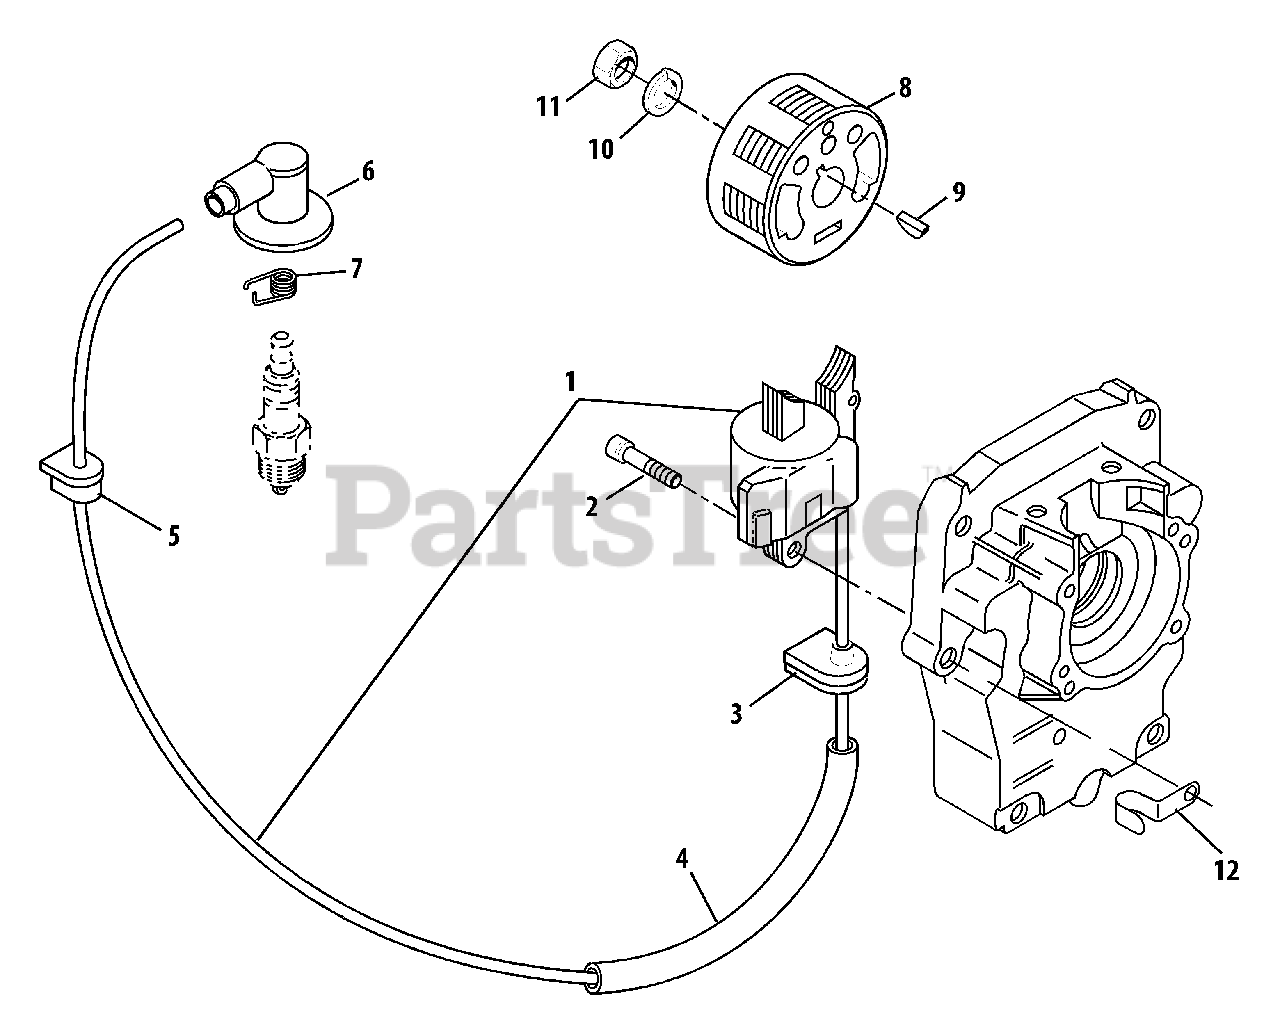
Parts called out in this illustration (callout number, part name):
1	COIL, IGNITION
2	BOLT 5
3	GROMMET
4	TUBE, INSULATOR
5	GROMMET
6	CAP, SPARK PLUG
7	TERMINAL, SPARK PLUG
8	FLYWHEEL
9	KEY, WOODRUFF 3×10
10	WASHER, SPRING 10
11	NUT 10×1.25
12	CLIP
